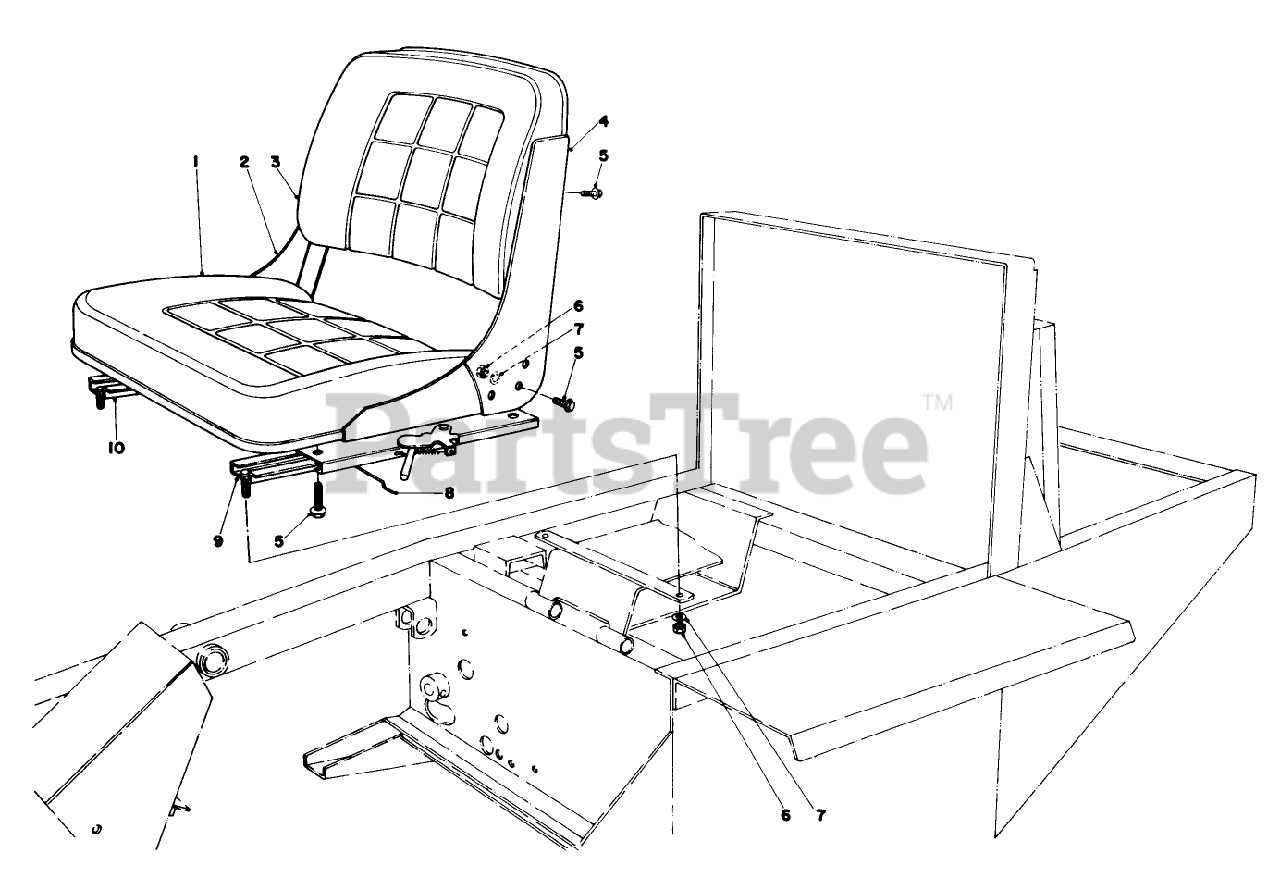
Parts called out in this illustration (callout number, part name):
1	Seat Cushion
2	RH RAIL
3	Backrest
4	LH RAIL
5	SCREW-HHF
6	NUT-HEX
7	WASHER-LOCK
8	Connecting Rod
9	Adjuster L.H.
10	Adjuster R.H.
